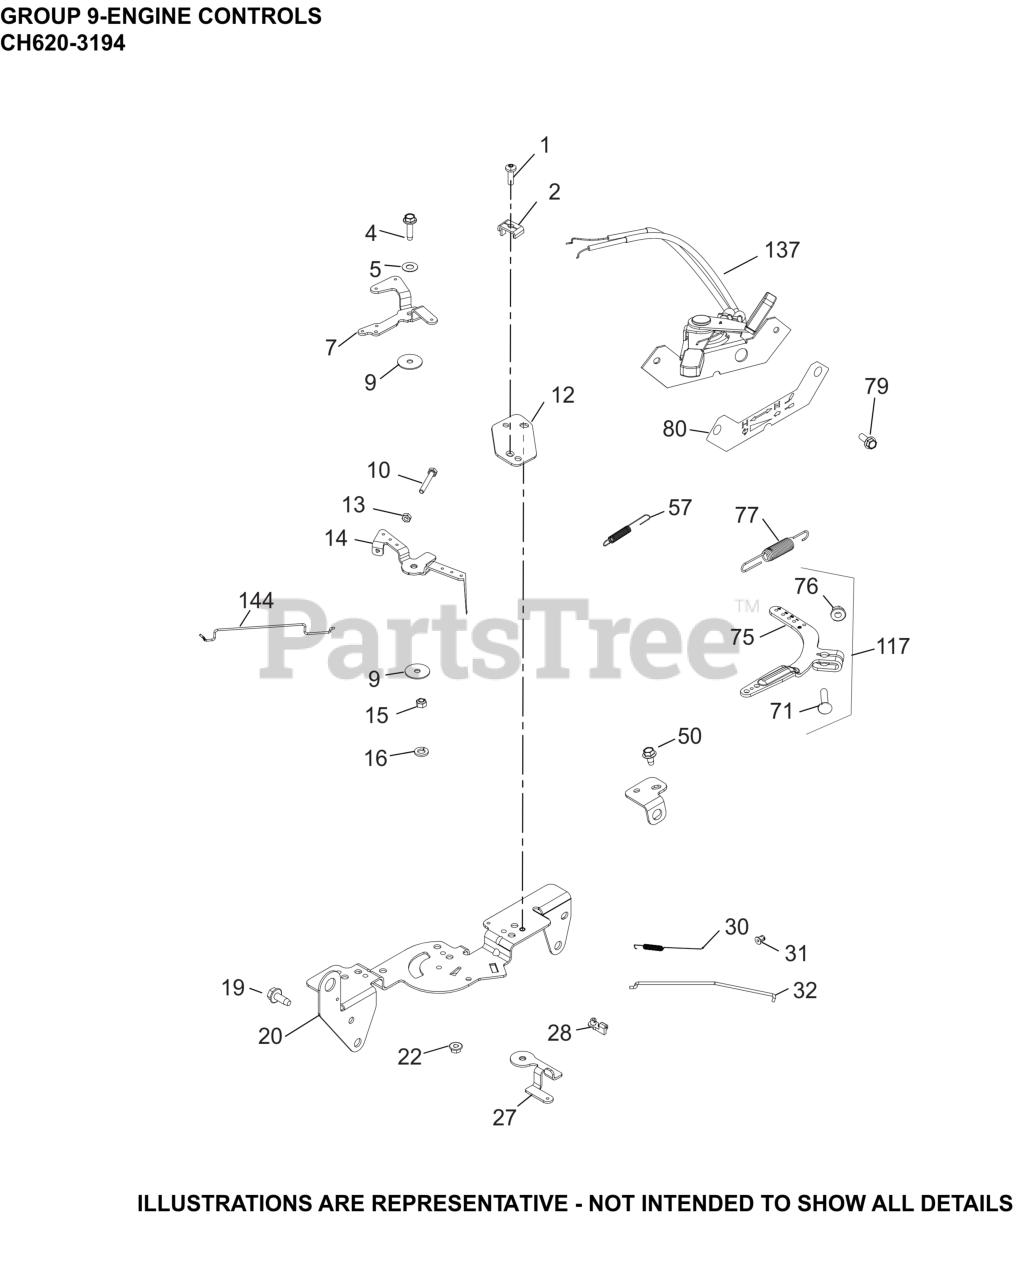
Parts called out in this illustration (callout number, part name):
1	SCREW, THREAD FORMING
2	CLAMP, CABLE CABLE
4	SCREW, THD FRM-USE 25 086 473-S
5	WASHER, SPRING 1/4"
7	LEVER, CHOKE
9	WASHER, FLAT 5.5 MM
10	SCREW, CAP M4X.7X30
12	BRACKET, CABLE SUPPORT
13	NUT, M4X0.7
14	LEVER, THROTTLE CONTROL
15	NUT, FLG M5X.8
16	WASHER, SPRING LOCK 1/4"
19	SCREW, THREAD FORMING
20	BRACKET, CONTROL
22	NUT, LOCK M5X.8
27	LEVER, THROTTLE ACTUATOR
28	BUSHING, THROTTLE LINKAGE
30	SPRING, LINKAGE
31	BUSHING, LINKAGE RETAINING
32	LINKAGE, THROTTLE
50	SCREW, THREAD FORMING
57	SPRING, THROTTLE LIMITER
71	BOLT, RD HD SQ NECK M6X1.0X25
75	LEVER, GOVERNOR - (#2409069S)
76	NUT, FLG M6X1.0
77	SPRING, GOVERNOR (BLUE)
79	SCREW, HI-LOW
80	DECAL, CONTROL PANEL
117	LEVER, GOVERNOR ASSEMBLY
137	CABLE ASSEMBLY, DUAL CONTROL
144	LINKAGE, CHOKE
